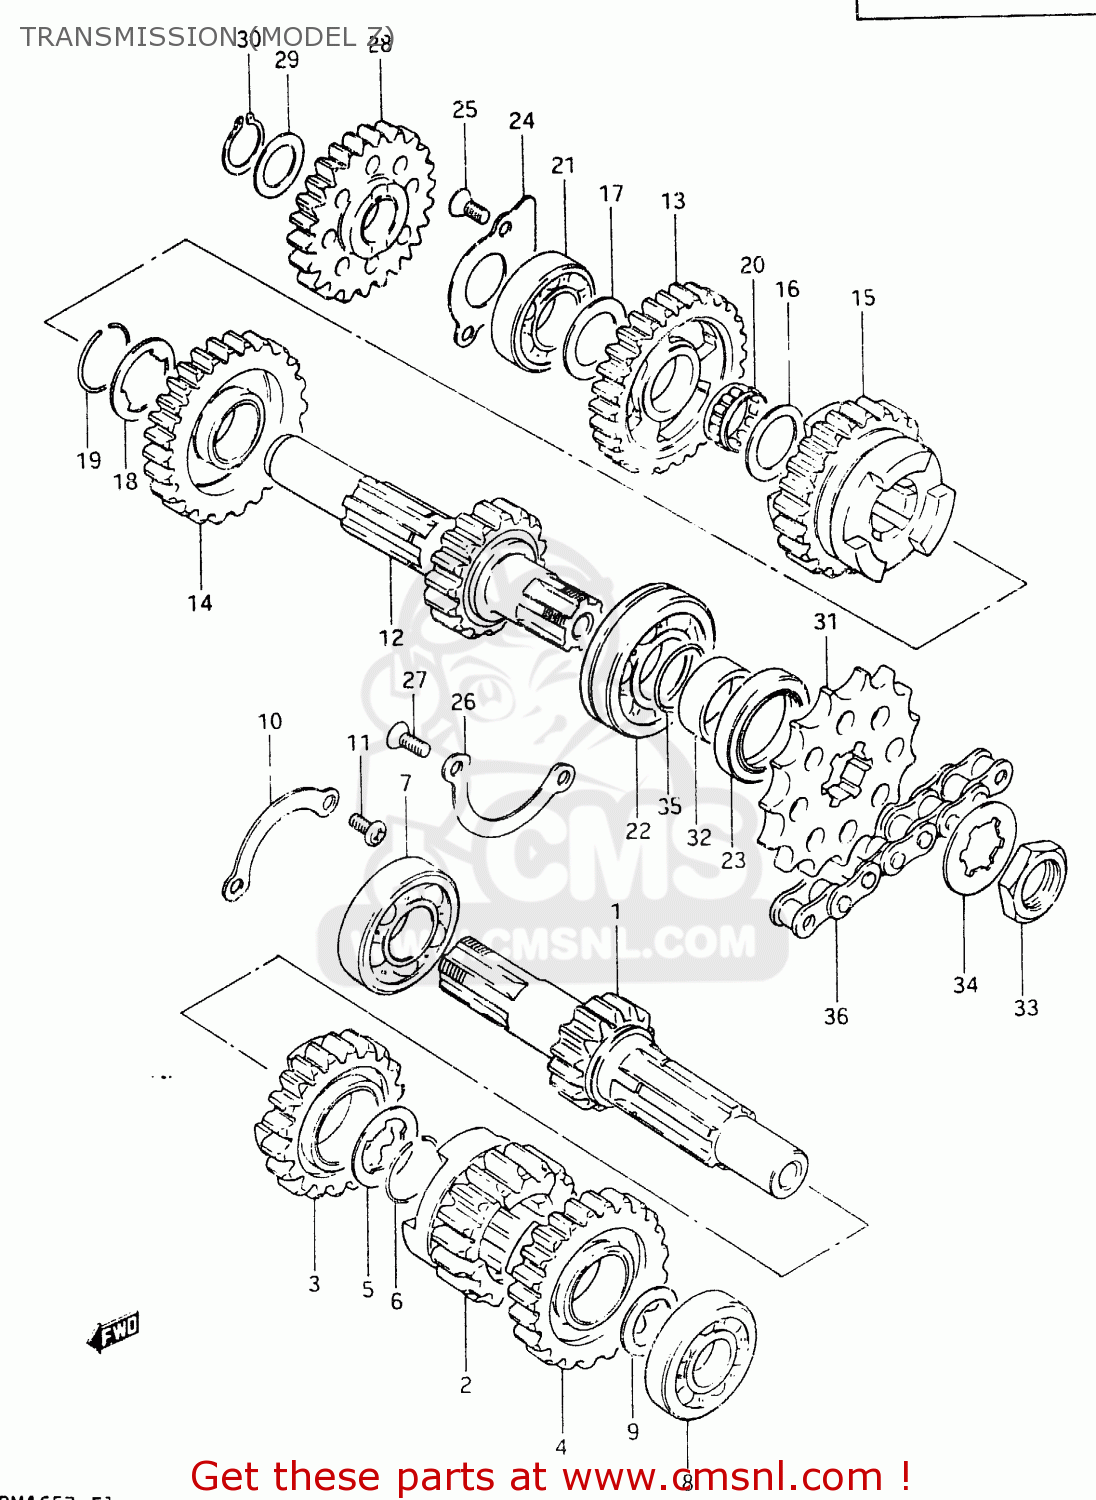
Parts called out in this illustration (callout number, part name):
1	SHAFT,COUNTER
2	GEAR,SECOND DRIVE
3	GEAR,THIRD DRIVE
4	GEAR,FOURTH DRIVE
5	WASHER
6	RING,SNAP
7	BEARING
8	BEARING, LH
9	WASHER
10	RETAINER,BEARING
11	SCREW 6X12
12	SHAFT,DRIVE
13	GEAR,FIRST DRIVEN
14	GEAR,SECOND DRIVEN
15	GEAR,THIRD DRIVEN
16	WASHER
17	WASHER
18	WASHER
19	CIRCLIP
20	BEARING(20X24X10).8
21	BEARING
22	BEARING(28X58X16)
23	SEAL,OIL(35X45X6)
24	RETAINER,DRIVESHAFT
25	SCREW
26	PLATE,DRIVESHAFT BEARING
27	SCREW
28	GEAR,KICK STARTER IDLE
29	WASHER,THRUST
30	CIRCLIP
31	SPROCKET,ENGINE(NT:13)
32	SPACER(28X35X11.4)
33	NUT
34	WASHER,LOCK
35	O RING(D:1.5,ID:27.7)
36	CHAIN ASSEMBLY,DRIVE
